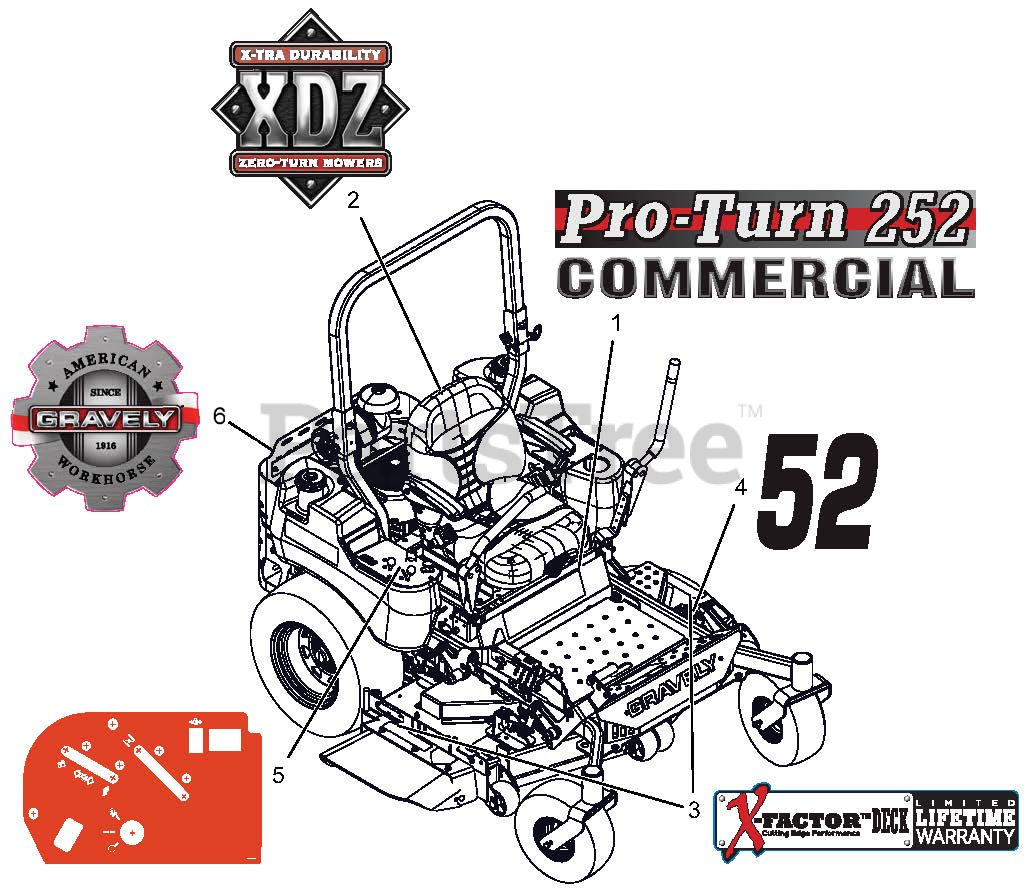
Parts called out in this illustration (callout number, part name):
1	DECAL, PRO-TURN 252
2	DECAL, XDZ 5"
3	DECAL-X-FACTOR DECK
4	DECAL, 52"
5	DECAL, CONTROL PANEL NON EFI
6	DECAL, GRAVELY HERITAGE-LARGE
